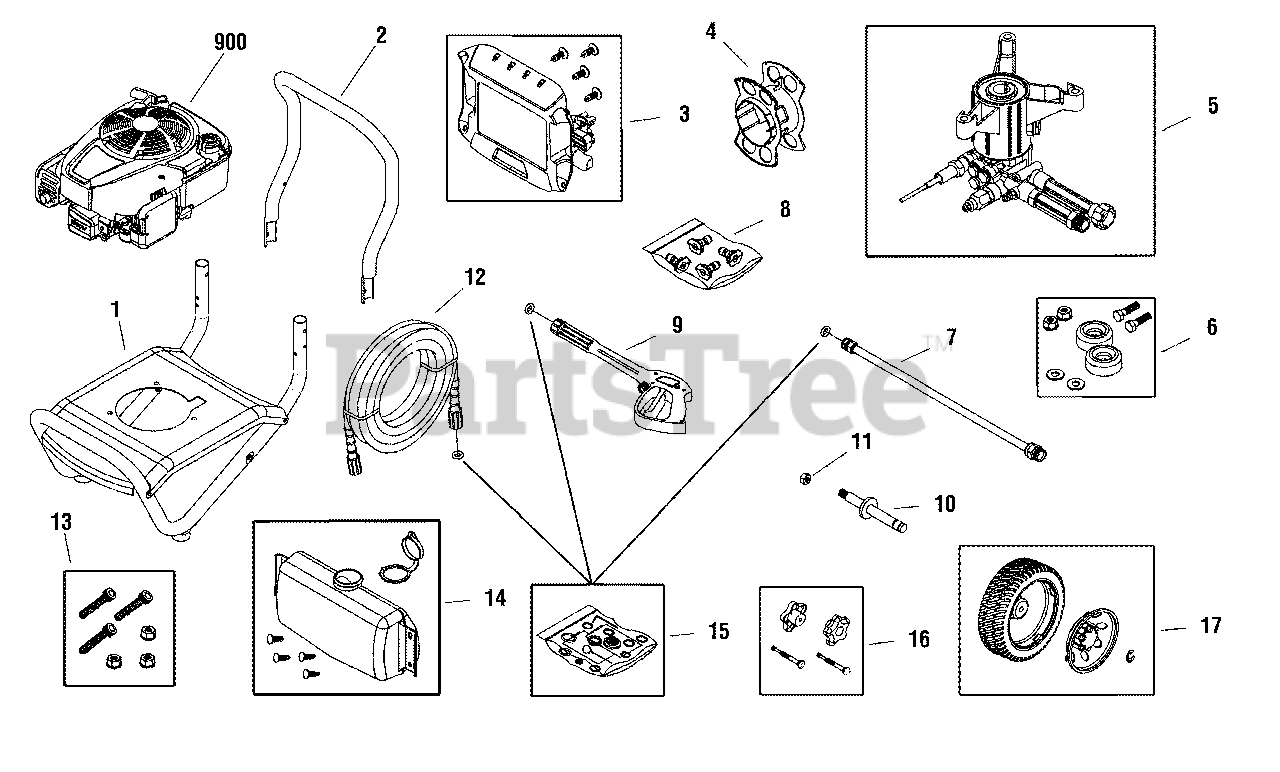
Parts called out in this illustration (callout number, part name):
6	MOUNT, Vibration
7	EXTENSION, QC
9	GUN
13	KIT, Hardware Pump Mounting
16	KIT, Hardware Handle
17	KIT, Wheel
